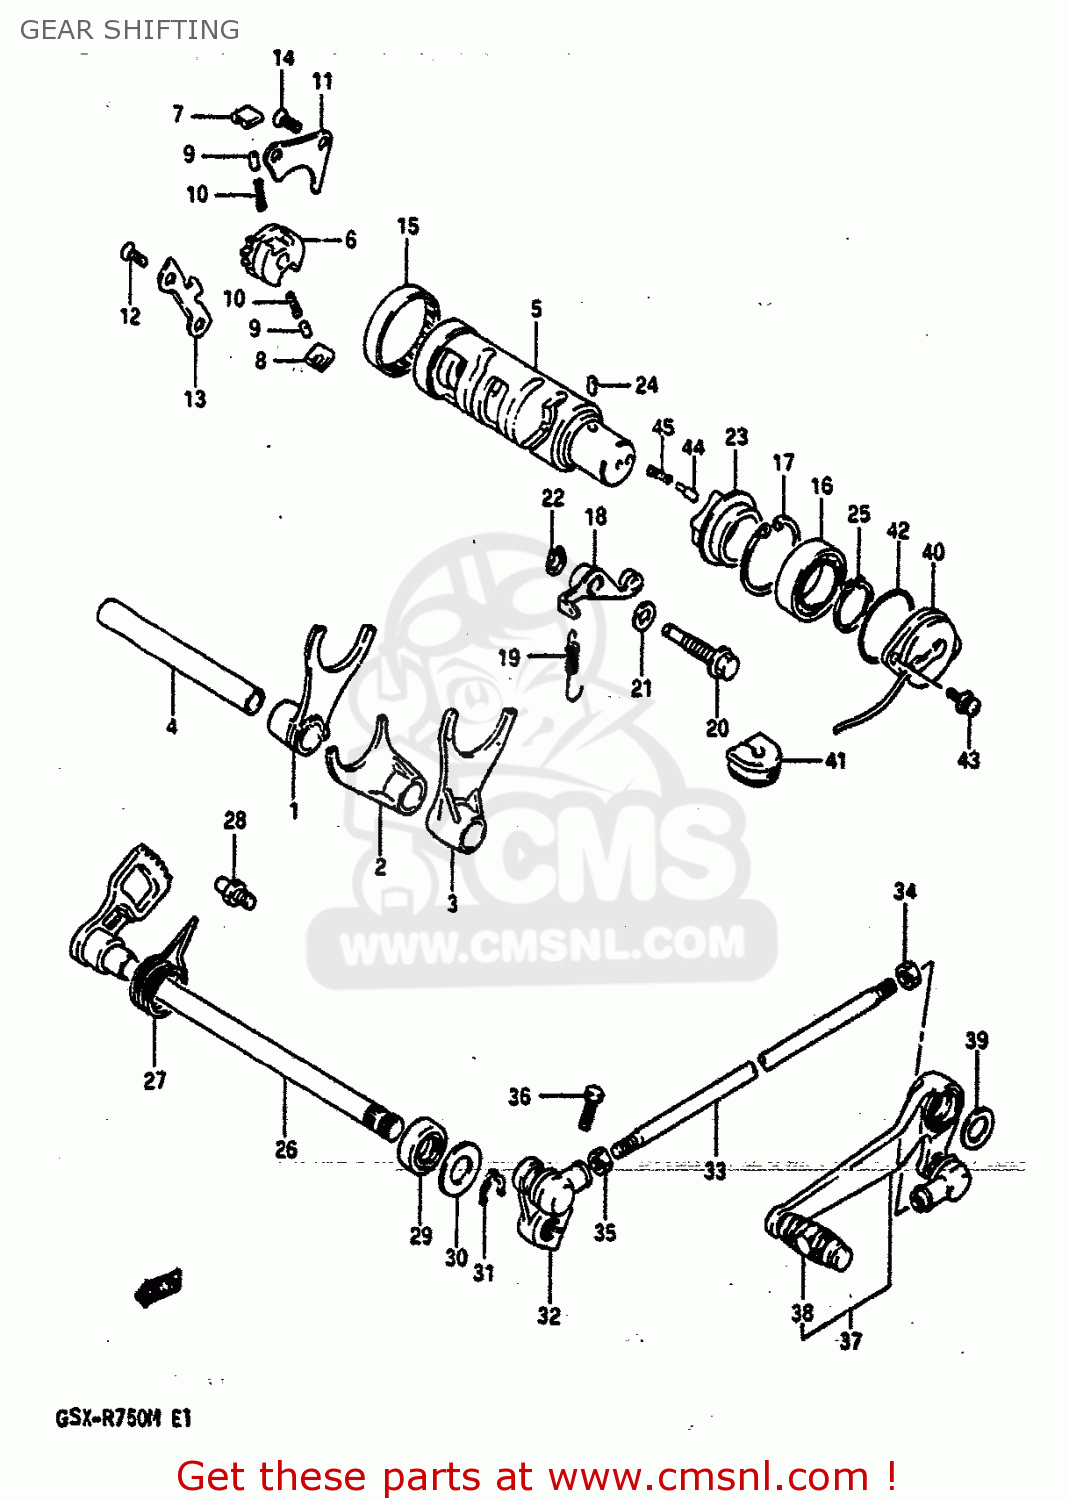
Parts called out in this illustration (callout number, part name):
1	FORK,GEAR SHIFT NO.1
2	FORK,GEAR SHIFT NO.2
3	FORK,GEAR SHIFT NO.3
4	SHAFT,GEAR SHIFT FORK(L:128)
5	CAM,GEAR SHIFT
6	GEAR,GEARSHIFT CAM DRIVE
7	PAWL,GEAR SHIFT NO.1
8	PAWL,GEAR SHIFT NO.2
9	PIN(5X8)
10	SPRING
11	LIFTER,GEAR SHIFT PAWL
12	SCREW
13	GUIDE,GEAR SHIFT CAM
14	SCREW
15	BEARING(43X49X12)
16	BALL BEARING
17	CIRCLIP,42MM
18	STOPPER,GEAR SHIFT CAM
19	SPRING
20	SHAFT,GEAR SHIFT CAM STOPPER
21	GASKET(10X14X3.6) (NAS)
22	CIRCLIP
23	PLATE,STOPPER
24	PIN 4X6
25	CIRCLIP,25MM
26	SHAFT,GEAR SHIFT
27	SPRING
28	STOPPER,GEAR SHIFT CAM
29	OIL SEAL
30	WASHER (12.5X27X1.6)
31	SPRING,RETAINER
32	ARM,GEAR SHIFT LINK
33	ROD,GEAR SHIFT LINK
34	NUT
35	NUT 6MM
36	BOLT
37	LEVER ASSEMBLY,GEAR SHIFTING
38	RUBBER,GEAR SHIFT PEDAL
39	WASHER(18X24X1)
40	TERMINAL BASE ASSY,NEUTRAL
41	GROMMET,LEADWIRE
42	O RING(D:2.4,ID:36.5)
43	SCREW
44	PIN(5X15.5)
45	SPRING
